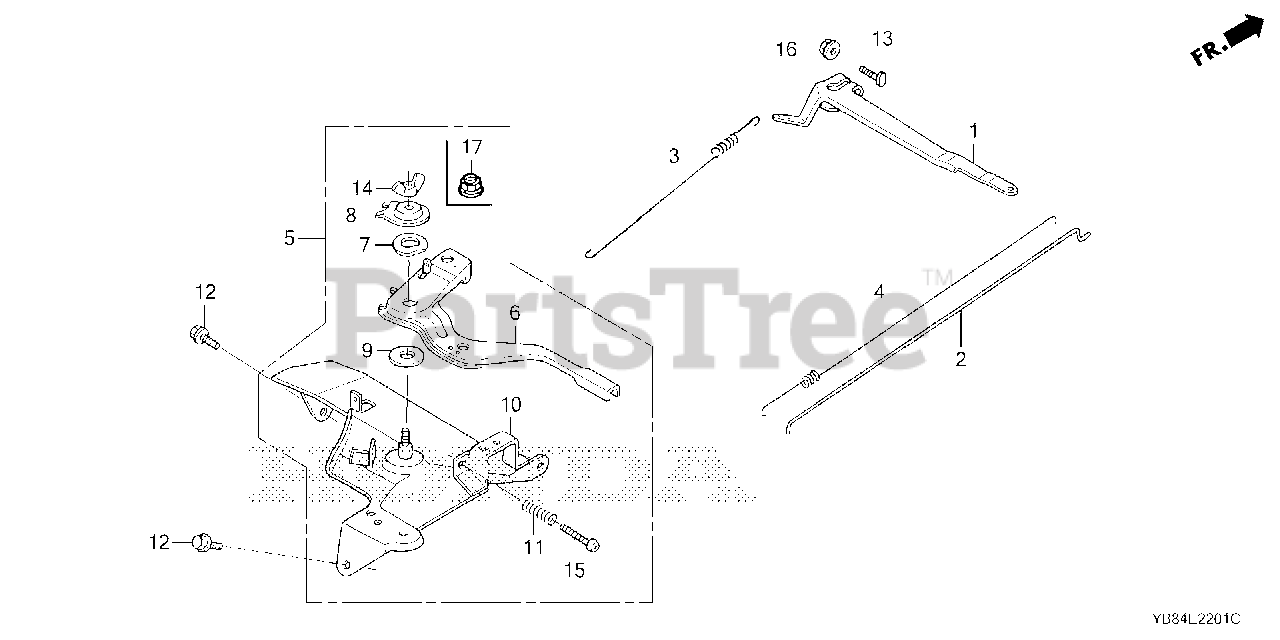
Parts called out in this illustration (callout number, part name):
1	ARM, GOVERNOR
2	ROD, GOVERNOR
3	SPRING, GOVERNOR (L=145.0MM) (WIRE DIAMETER 1.0MM)
3	SPRING, GOVERNOR (L=142.0MM)
4	SPRING, THROTTLE RETURN
5	CONTROL ASSY.
6	LEVER, CONTROL
7	SPRING, LEVER
8	WASHER, CONTROL LEVER
9	SPACER, CONTROL LEVER
10	BASE, CONTROL
11	SPRING, CONTROL ADJUSTING Use from Engine SN 2327377.
12	BOLT, FLANGE (6X12) (CT200)
13	BOLT, GOVERNOR ARM
15	SCREW, PAN (5X28)
16	NUT, FLANGE (6MM)
17	NUT, SELF-LOCK (6MM)
